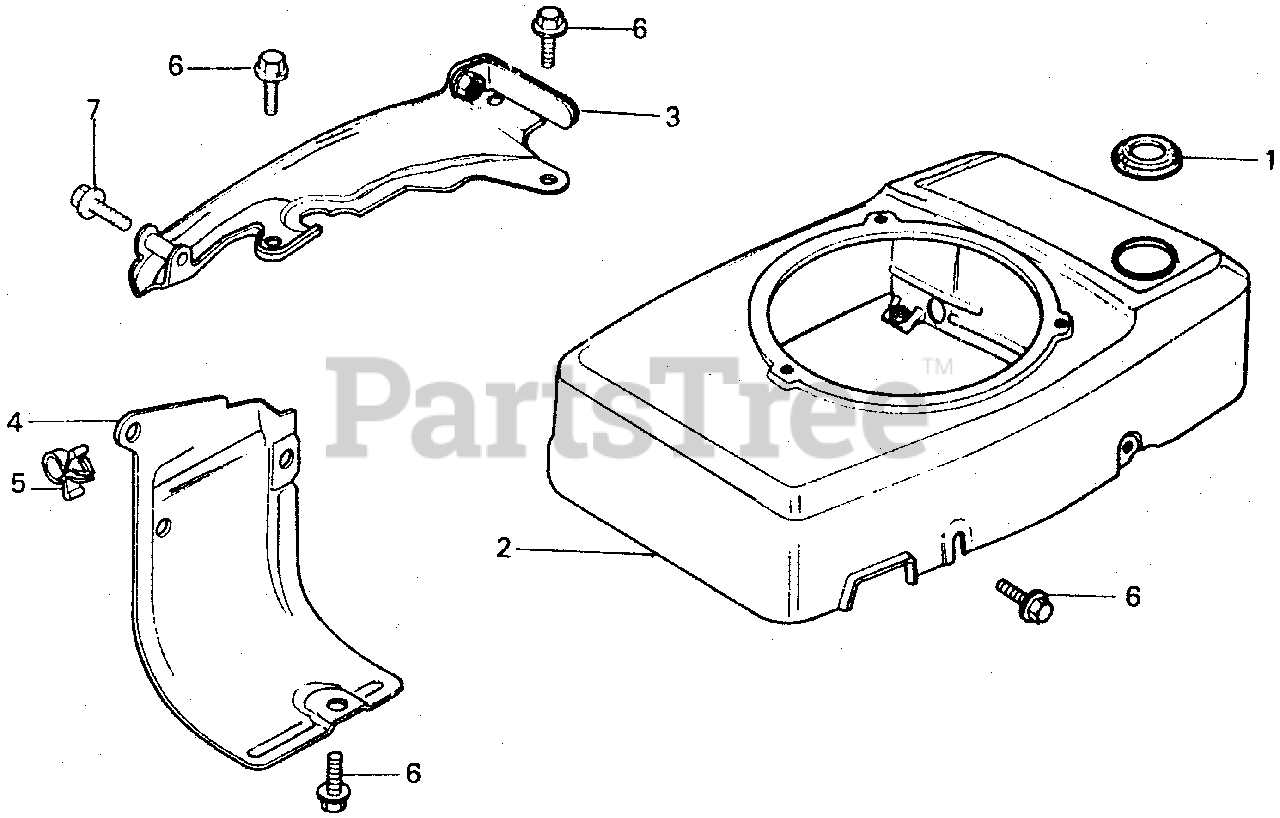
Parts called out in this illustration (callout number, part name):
1	SEAL, FILLER NECK
3	PLATE, SIDE
6	BOLT, FLANGE (6X12) (CT200)
7	BOLT, FLANGE (6X32) (CT200)
